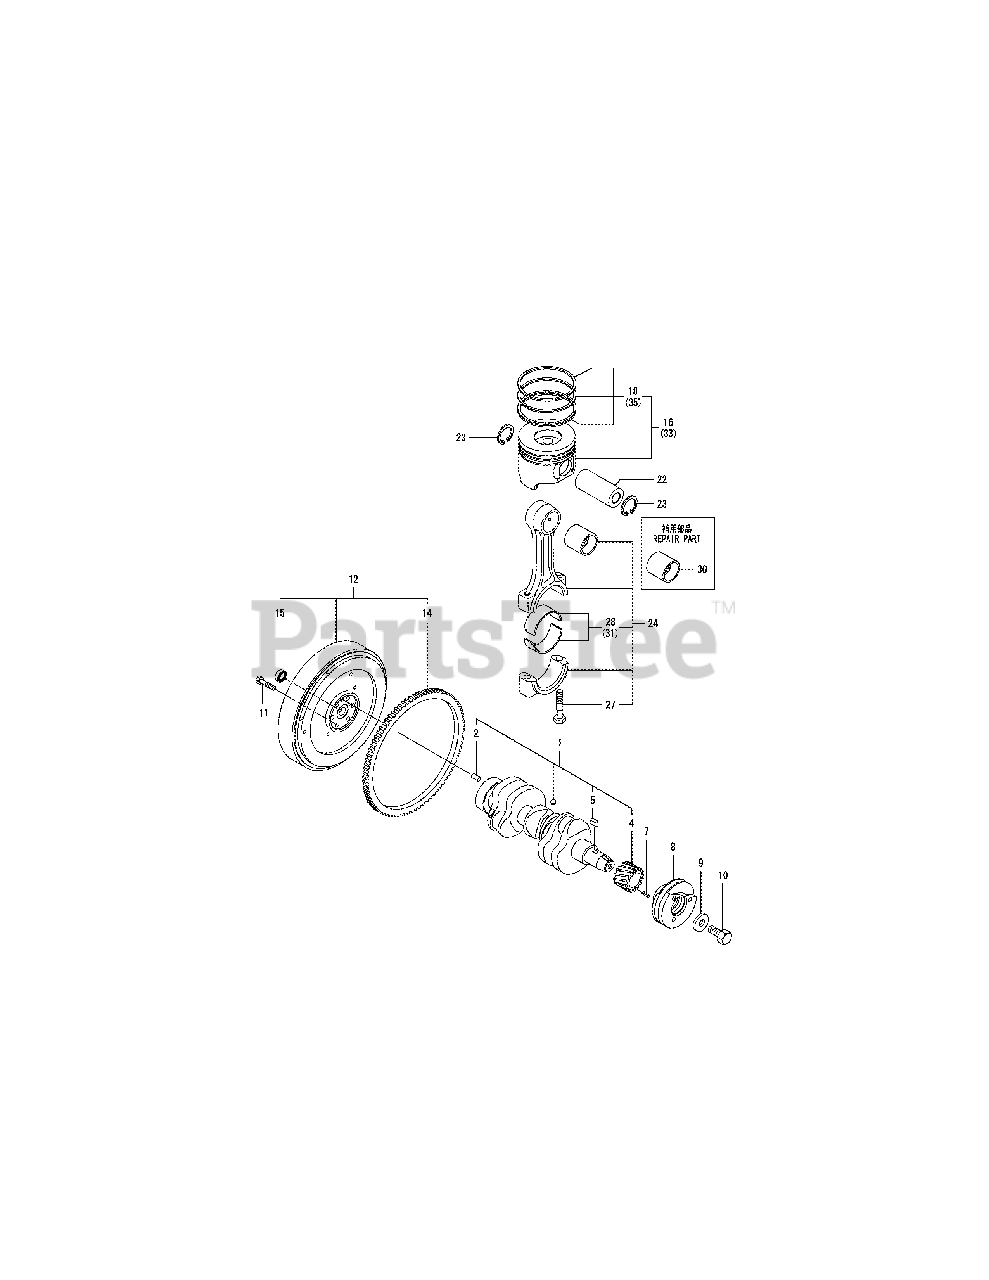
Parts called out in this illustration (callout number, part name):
1	CRANKSHAFT ASSY
2	PARALLEL PIN 8X16
4	GEAR, CRANKSHAFT
7	SPRING PIN 3X10
8	V-PULLEY, CRANKSHAFT
10	BOLT, V-PULLEY
11	BOLT, FLYWHEEL
18	RING SET, PISTON
22	PIN, PISTON(D26,L70)
24	ROD ASSY, CONNECTING
27	BOLT, CONNECTING ROD
28	METAL, CRANKPIN
30	BUSH, PISTON PIN
31	METAL.PIN US=0.25
33	PISTON W/RING OS=.25
35	RING SET O.S=0.25
